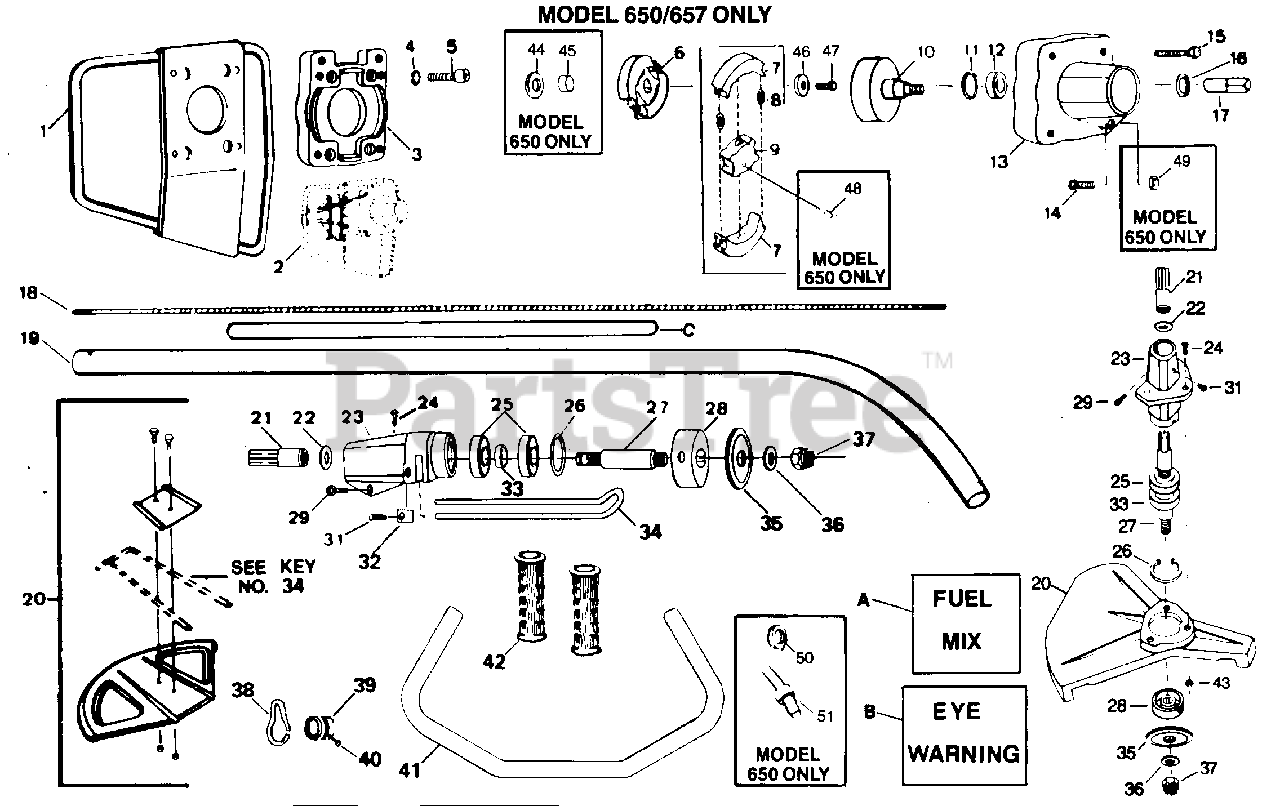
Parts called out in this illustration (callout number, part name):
1	Motor Leg
2	Muffler Guard
3	Plate Adaptor Engine
4	Washer, Lock 9/16" O.D. 5/16" I.D.
5	Screw, Socket Hd. #5/16 - 18 x 3/4"
6	Clutch Assembly
6	Model 657
6	Model 650
7	Shoe, Clutch
8	Spring, Clutch, Yellow
9	Rotor Hub, w/Integral Keepers
9	Model 657
9	Model 650
10	Drum & Arbor
11	Retaining Ring
13	Housing, Clutch w/Bearing/Get. Ring
14	Model 657
14	Model 650
15	Screw, Hex Hd #1/4 - 20 x 2"
16	Washer, Drive Shaft, Upper & Lower
17	Coupling Squared
18	Flexible Drive Shaft
18	Previous Style
18	Current Style
19	Drive Shaft Housing
19	Previous Style
19	Current Style
20	Shield Kit
20	Previous Style (#34 not included)
20	Current Style
21	Coupling Squared
22	Washer, Upper & Lower Drive Shaft
23	Previous Style
23	Current Style
24	Screw
24	Previous Style
24	Current Style
25	Bearing, Ball
26	Retaining Ring
27	Arbor Shaft
28	Cup Washer, Arbor, Keyed
29	Screw, Soc. Hd. #5/16 - 18 x 1"
31	Screw #1/4 - 20 x 1/2"
32	Washer - Previous Style
34	Lower Head Support Brace - Previous Style
35	Washer, Lower Arbor
36	Washer
36	Previous Style
36	Current Style
37	Nut, Hex #7/16 - 20
39	Collar, Swivel
40	Screw, Set Thumb
41	Handlebar
42	Grip, Handlebar
42	Model 657
42	Model 650
43	Nut - 10-32-Current Style
48	Woodruff Key
49	Lock Nut
50	Pilot Washer
51	Grommet - Drive Shaft
A	Decal - Fuel Mix
B	Decal - Choke/Eye Warning
C	Decal-Safety Label
